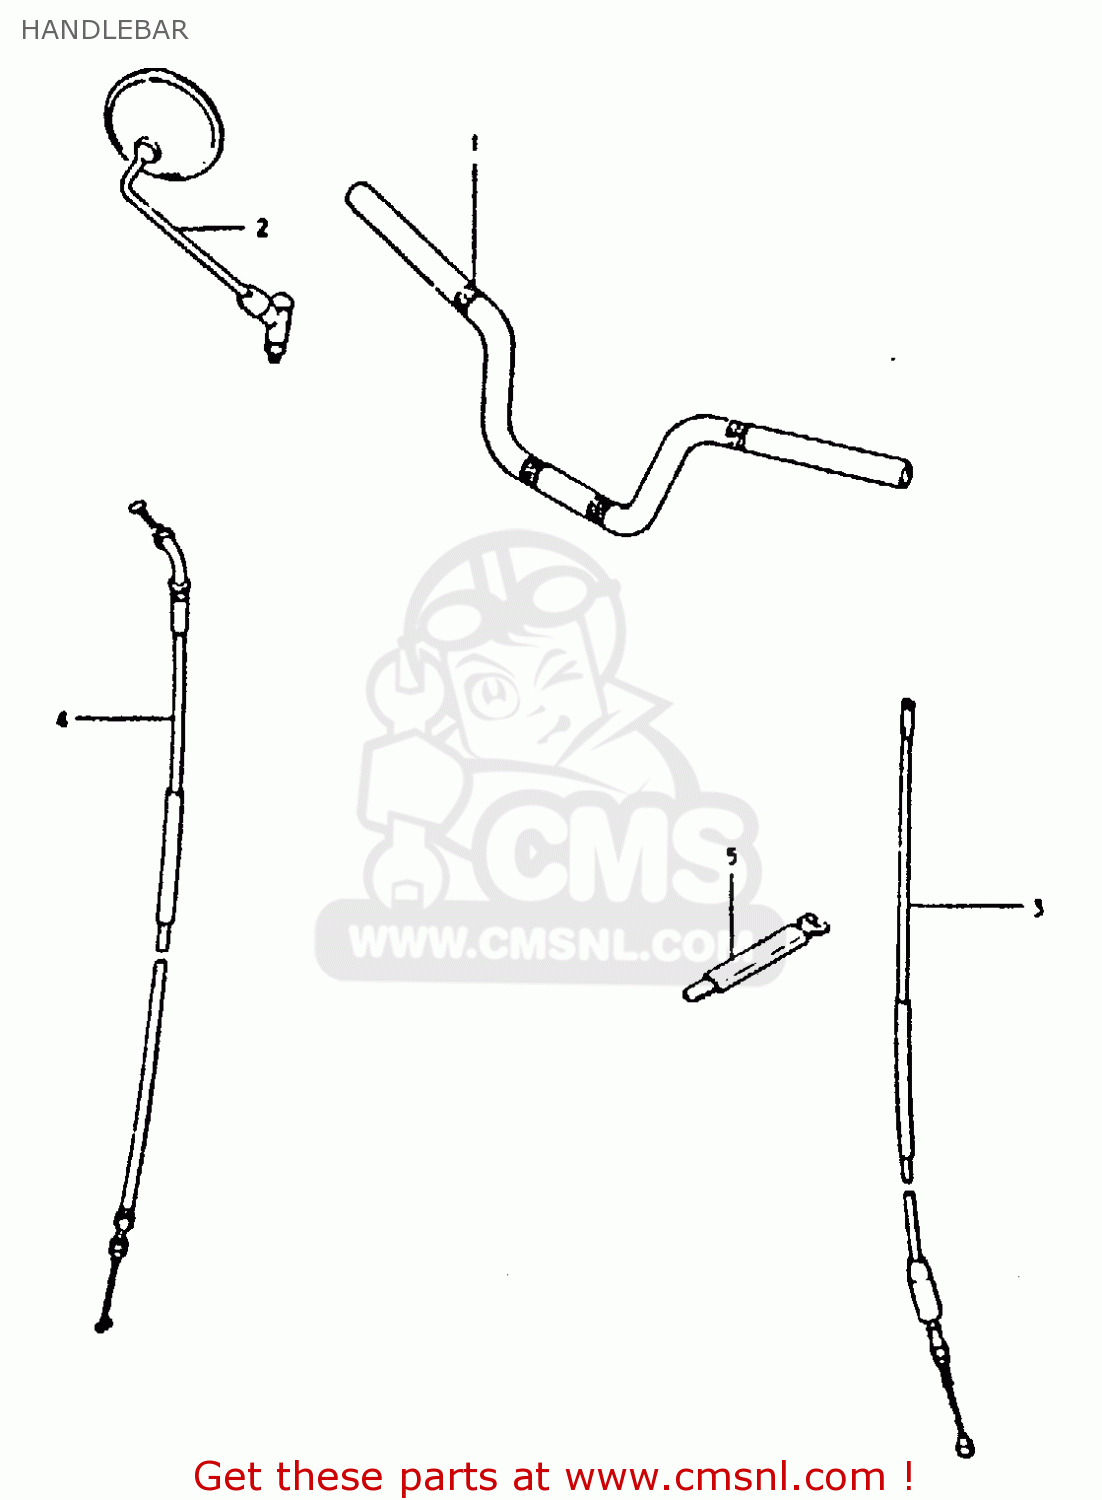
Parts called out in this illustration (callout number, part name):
1	HANDLEBAR
2	MIRROR ASSY,RR VIEW
3	CABLE ASSEMBLY,CLUTCH
4	CABLE ASSEMBLY,THROTTLE
5	CLAMP
